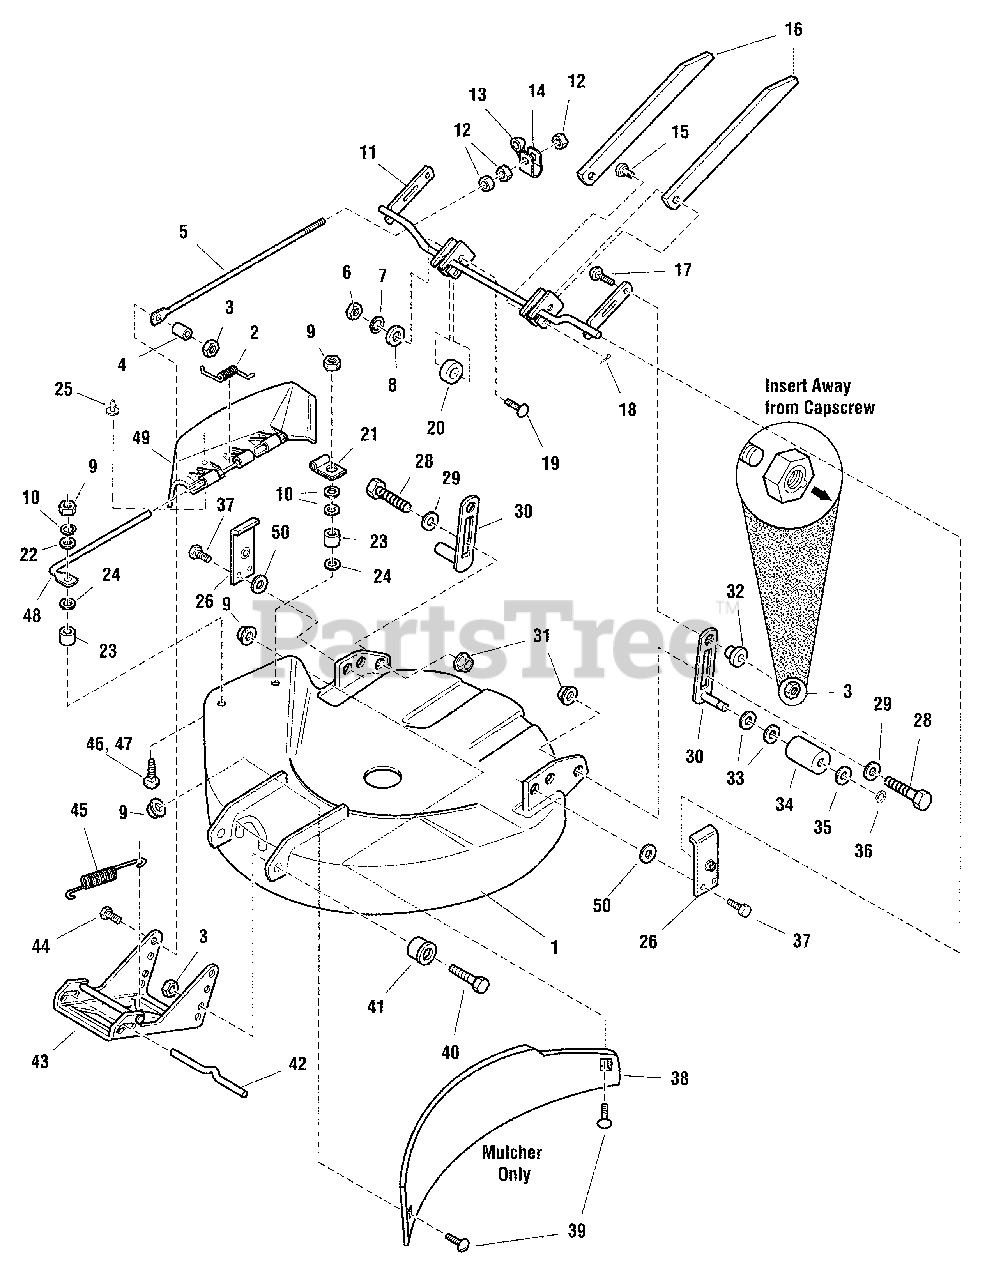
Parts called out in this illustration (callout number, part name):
1	HOUSING ASSEMBLY, 30" (Red)
2	SPRING, Torsion
3	NUT, Hex Flange, 3/8-16
5	ROD, Adjustment
6	NUT, Hex Flange Whiz Lock, 5/16-18
7	LOCKWASHER, 5/16 (Domestic Only)
8	WASHER, 5/16
9	NUT, Hex ESNA, 1/4-20
10	WASHER, Plain 1/4 Black (Min 1 Required for Export)
11	ARM ASSEMBLY, Mower
12	NUT, Hex Jam, 1/2-13
13	SPACER
15	PIN, Locking
16	BAR, Mower Transport
17	BOLT, Carriage, Short Neck, 3/8-16 x 1-1/2
18	PIN, Retaining
19	BOLT, Carriage, 5/16-18 x 1 1/4
21	CLAMP, Wire, 5/16 Diameter
22	WASHER, Plain (1 Required for Export)
23	SPACER (Export)
24	PUSHNUT, 1/4
25	PLUG, Hole
26	PLATE, Pivot Support
28	BOLT, Shoulder, 3/8-16 X 1.34, 1/2 Shoulder
29	WASHER, Flat
30	SUPPORT ASSEMBLY, Roller
31	NUT, Hex, Flange, Whizlock, 3/8-16
32	NUT, Hex Adjusting, 11/16
33	WASHER, 5/8
35	WASHER, Plain, 21/32
36	RING, Retaining
37	CAPSCREW, Taptite, 5/16-18 x 3/4
38	PLATE, Discharge (30" Mulcher)
39	CARRIAGE BOLT, 5/16-18 x 3/4, G5
40	CAPSCREW, Hex, 3/8-16 x 1-3/8
41	SPACER, 3/8 x 3/4 x 3/4
42	ROD, 3/8 x 8
43	HITCH ASSEMBLY
44	CAPSCREW, Hex Head, 3/8-16 x 1
46	CARRIAGE BOLT, 1/4-20 x 3/4
47	CARRIAGE BOLT, 1/4-20 x 1-1/4 (Export)
48	ROD, Deflector
49	DEFLECTOR, Plastic
50	WASHER, Flat 3/8 (Domestic Only)
